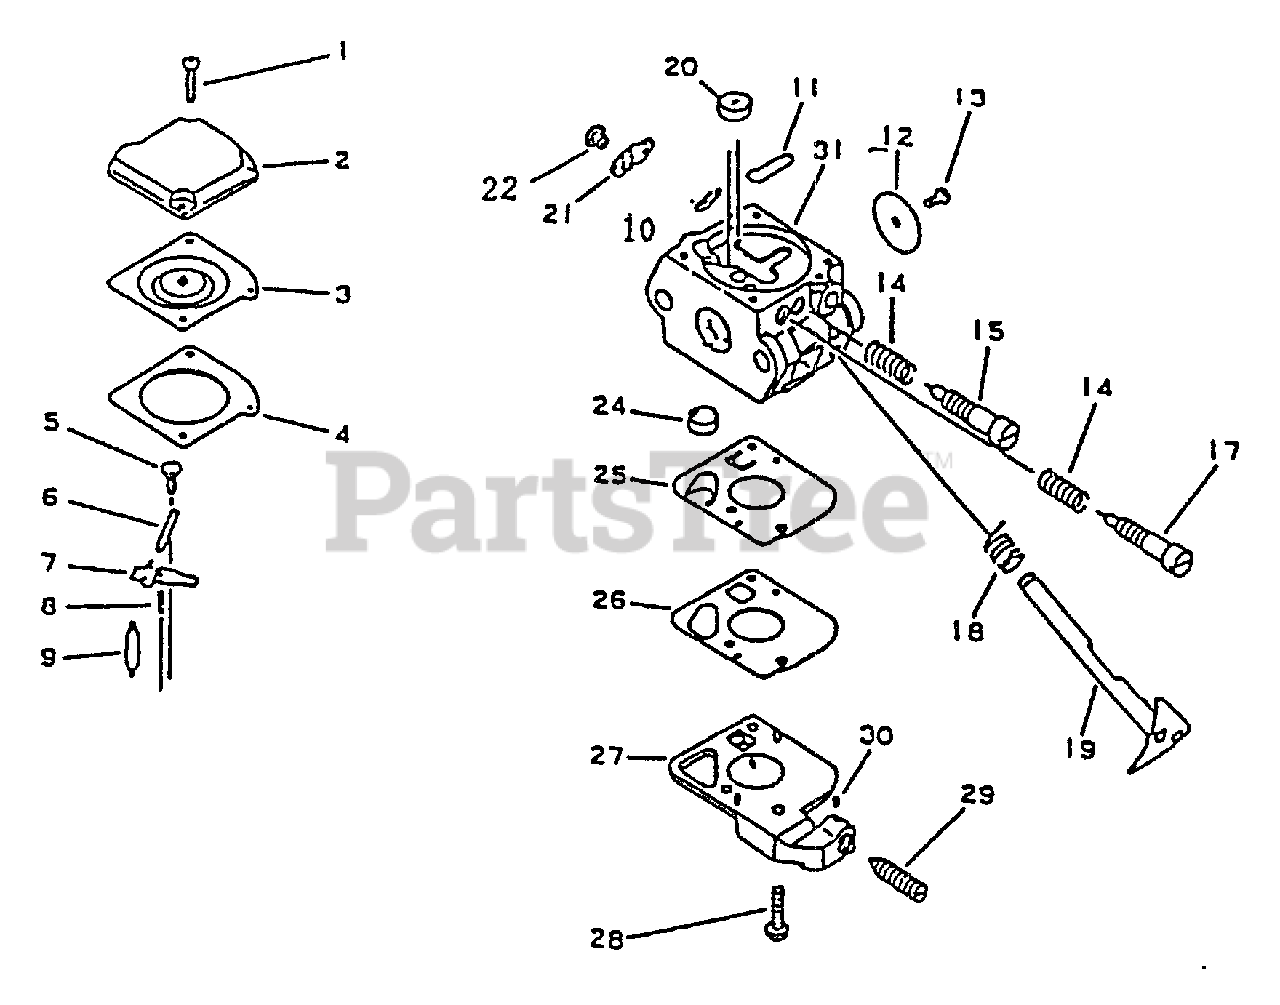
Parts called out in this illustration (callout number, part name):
2	COVER, DIAPHRAGM
3	DIAPHRAGM
4	GASKET, METERING
6	PIN, METERING LEVER
7	LEVER, METERING
8	SPRING
9	VALVE, NEEDLE
11	PLUG, WELCH
12	VALVE, THROTTLE
13	SCREW
14	SPRING, NEEDLE
15	NEEDLE, HIGH SPEED
17	NEEDLE, LOW SPEED
18	SPRING, THROTTLE RETURN
19	SHAFT, THROTTLE
20	NOZZLE, CHECK VALVE
21	LEVER, THROTTLE
22	SCREW
24	STRAINER
25	DIAPHRAGM, PUMP
26	GASKET, PUMP
27	COVER, PUMP
29	SCREW, IDLE ADJUST
30	PIECE, FRICTION
31	BODY, CARBURETOR
